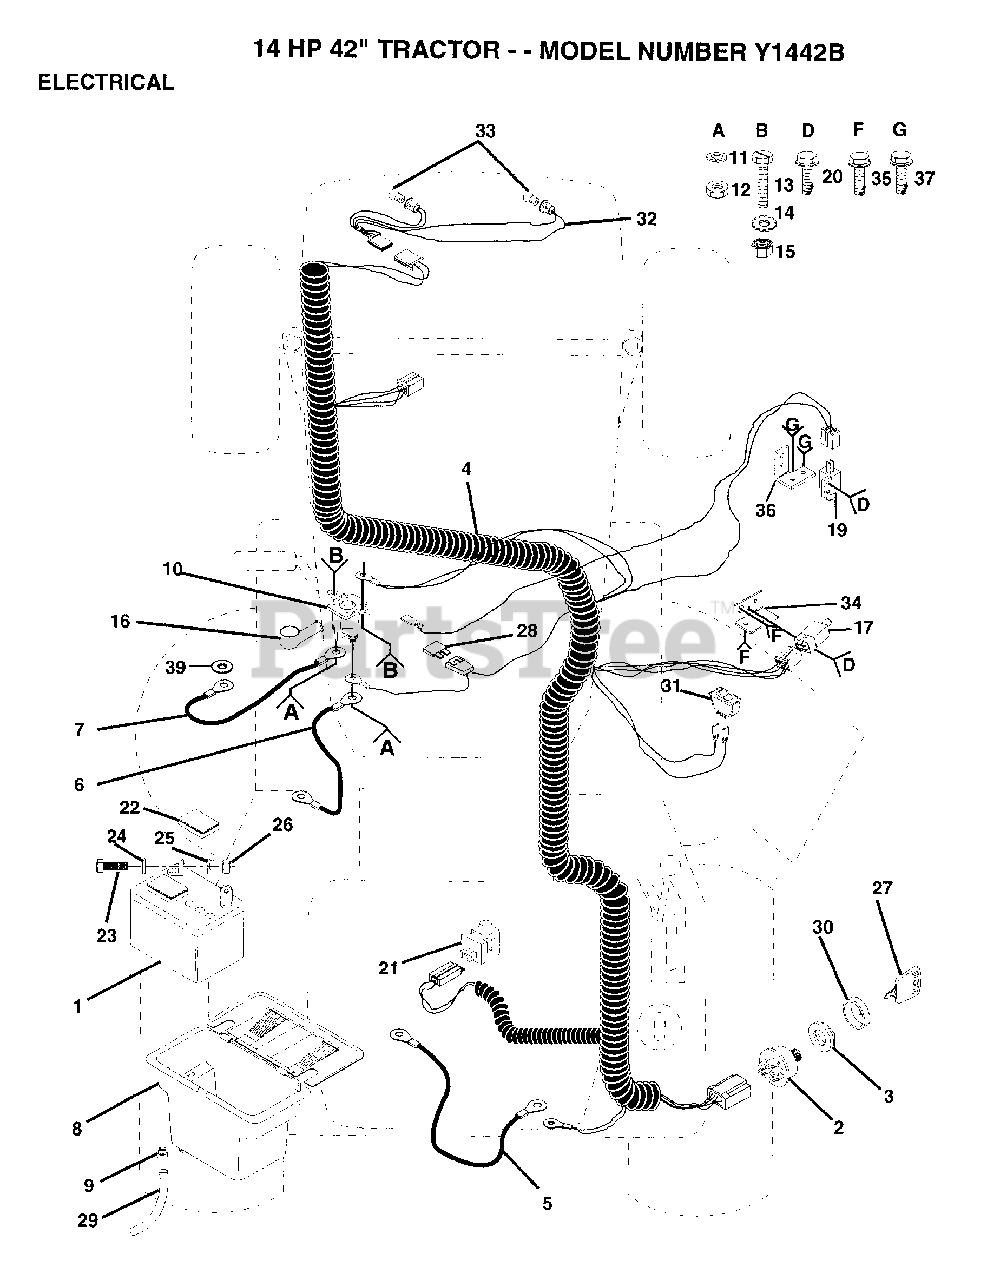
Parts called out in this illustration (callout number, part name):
3	NUT IGNITION
4	HARNESS.IGN.KOH
5	CABLE T
7	"CABLE T, BATTERY"
9	HOSE CLAMP T
10	DECAL.GRILL.LT
12	NUT
13	BOLT
15	NUT
17	SWITCH-INTER. GT
19	SWITCH INTERLOCKT
20	SCREW
21	SWITCH SEAT
22	"CAP,BATTERY "
23	BOLT LT
24	WASHER
25	LOCKWASHER
27	KEY
28	FUSE HYT
29	"DRAIN TU T, BATT"
31	SWITCH LT
34	BRACKET LT
35	SCREW
36	SWITCH BRACKET
37	SCREW
39	LOCKWASHER
